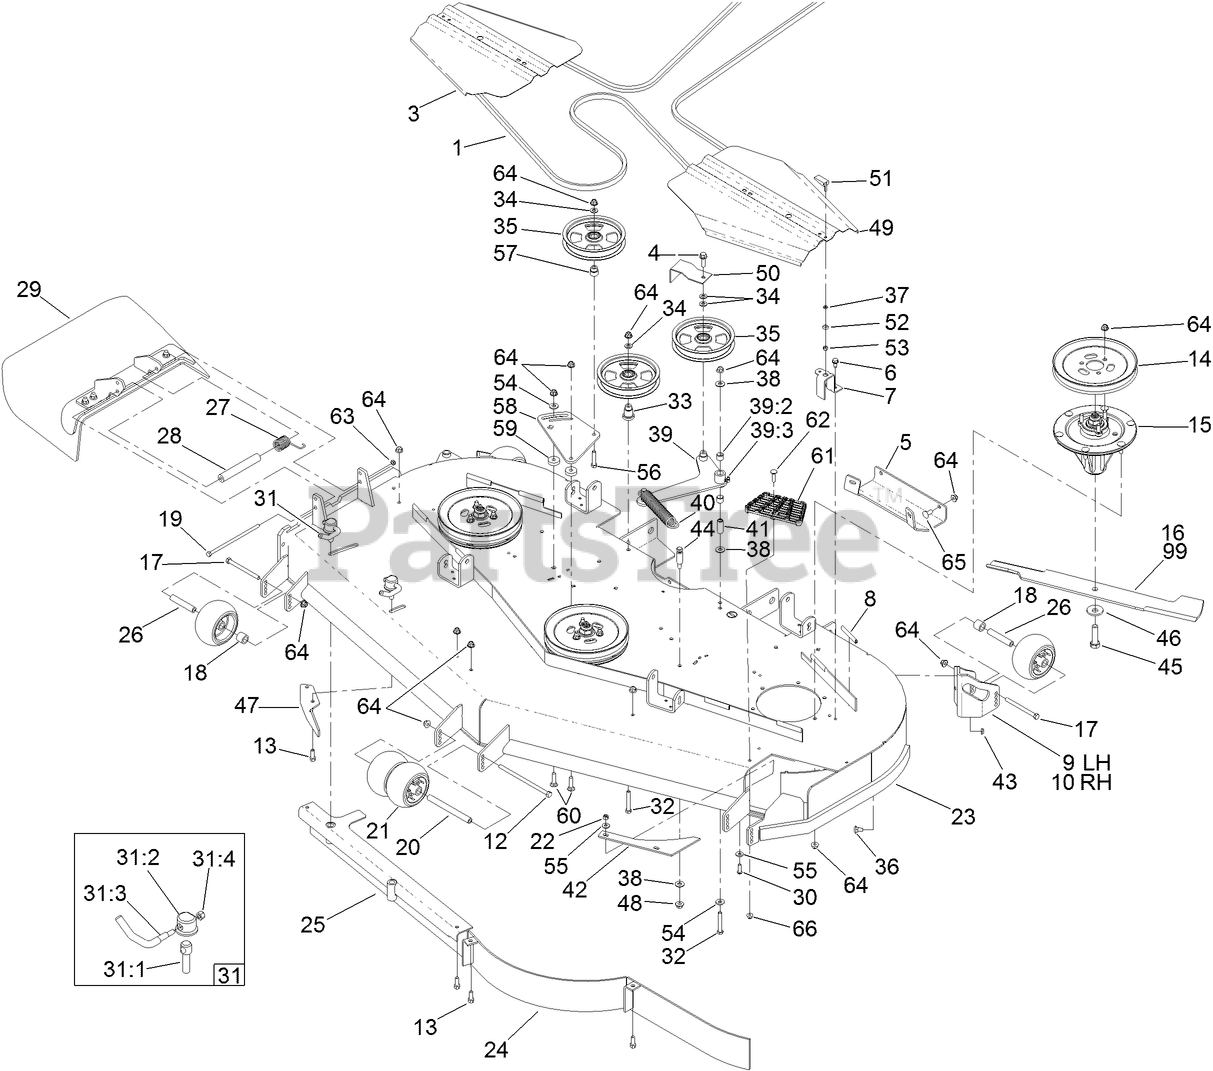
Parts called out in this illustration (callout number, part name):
3	COVER-BELT, RH
4	SCREW-HHF
5	PLATE-SKID
6	SCREW-HWHTF
7	BRACKET-COVER
8	STRIP-SEAL
9	MOUNT-WHEEL, LH
10	MOUNT-WHEEL, RH
12	SCREW-HH
14	PULLEY
15	SPINDLE ASM
16	BLADE-HI FLOW, 24.5 INCH
17	SCREW-HH
18	TUBE-SPACER
19	SCREW-HH
20	SPACER-WHEEL
21	ROLLER-SCALP, ANTI
22	NUT-LOCK, NI
23	DECK DECAL ASM
25	BAFFLE ASM
26	TUBE-SPANNER
27	SPRING-TORSION
28	SPACER
29	RUBBER DEFLECTOR ASM
30	SCREW-HSBH
31	LEVER ASM
31:1	SCREW-LOCK
31:2	CAP-LOCK
31:4	NUT-LOCK, NI
32	SCREW-HH
33	MOUNT-PULLEY
34	WASHER-FLAT
35	PULLEY-IDLER, FLAT
36	SCREW-HH
37	WASHER
38	WASHER-FLAT
39	DECK IDLER ARM ASM
39:2	SLEEVE-BEARING
39:3	FITTING-GREASE, 90 DEG
40	SPRING-EXTENSION
41	BUSHING
42	PLATE-TURBO
44	PIN-THREADED, SPRING ANCHOR
45	SCREW-BLADE
46	WASHER-BLADE BOLT, HEAVY
47	BAFFLE-DISCHARGE
48	NUT-HF
49	COVER-BELT, LH
50	GUIDE-BELT
51	HANDLE-LATCH, SWELL
52	BUSHING-LATCH, SWELL
53	NUT-LOCK, HH
54	WASHER-BELLEVILLE
55	WASHER-SPRING
56	SCREW-HH
57	BUSHING-IDLER
58	PLATE-IDLER
59	SPACER
60	SCREW-HH
61	STEP-DECK
62	SCREW-CARR
63	NUT-LOCK, NI
64	NUT-HF, NI
65	SCREW-CARR
66	NUT-HF, NI
99	BLADE-ATOMIC, 24.5IN
99	BLADE-LO FLOW, 24.5IN
99	BLADE-MID FLOW, 24.5IN
99	BLADE-RECYCLER, 24.5IN
